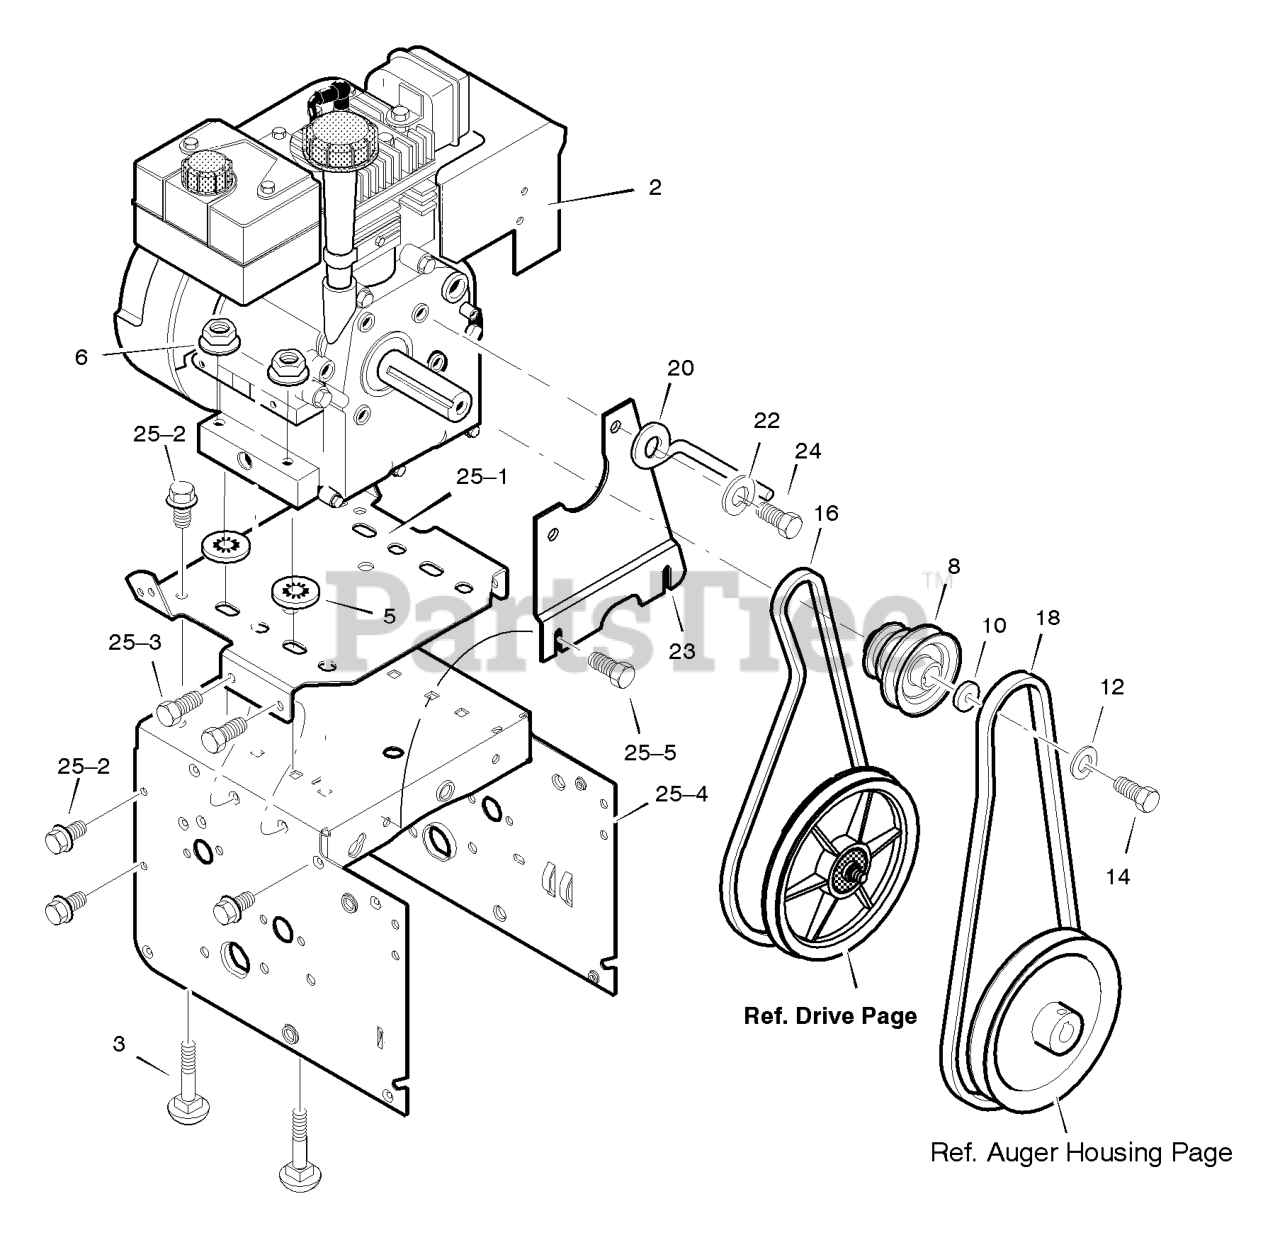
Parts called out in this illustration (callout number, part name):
2	ENGINE
3	BOLT, CARRIAGE 5/16-18
5	RETAINER, PUSH
6	NUT, HEX 5/16-18
8	PULLEY, ENGINE
10	WASHER
12	WASHER .38ID
14	SCREW, 3/8-24 x 1.00
16	BELT, V 3L 33.13LG
18	BELT, V 4L 38.1MF16" 5-10
20	GUIDE, BELT
22	WASHER, SPTLK .31X.58X.08
23	PLATE, ANTI VIBRATION
24	SCREW, 5/16-24 x 1.00
25	FRAME ASSEMBLY
25-1	PLATE, ENGINE MOUNT
25-2	SCREW, TAP 1/4-20 X .63
25-3	SCREW, TAP 5/16-18 X .50
25-4	FRAME, MOTOR BOX
